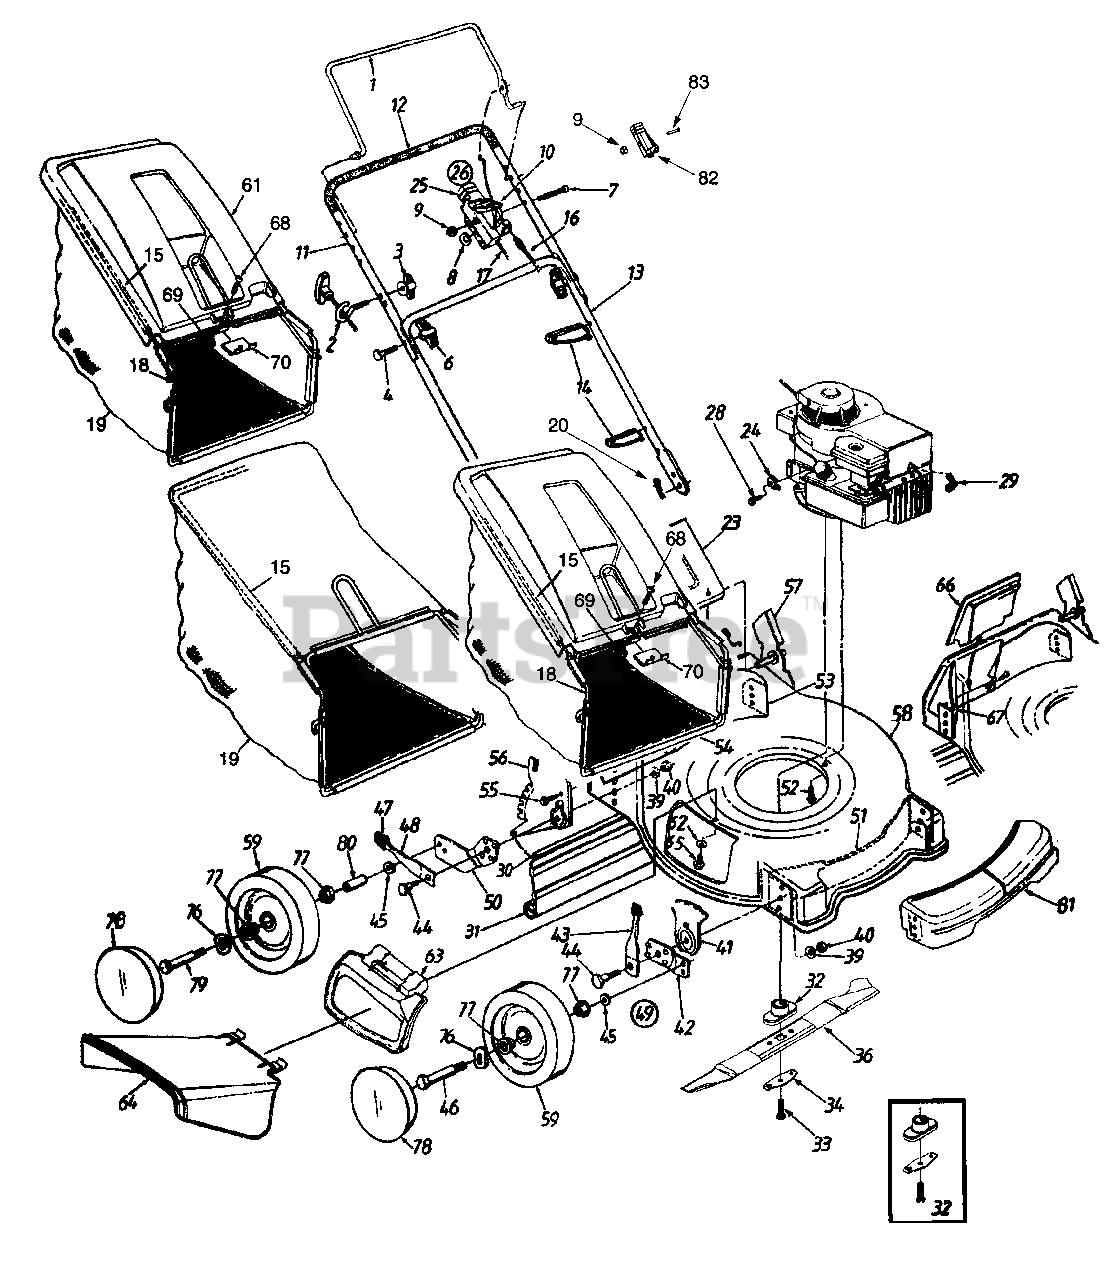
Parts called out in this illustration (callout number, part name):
1	Control Handle Ass'y. (Deluxe)
2	Rope Guide
3	Handle Knob 1/4-20 Thd.
4	Curved Hd. Bolt 5/16-18 x 2" Lg.
6	Hand Knob
7	Oval C-Sunk Mach. Scr.
8	Spr. Wash..66" I.D.
9	Hex L-Nut 1/4-20 Thd.
10	Throttle Lever
14	Cable Tie
16	Control Cable - 51"
17	Throttle Control Wire - 42"
20	Int. Cotter Pin 5/16" Dia.
25	Throttle Body
26	Throttle Box
28	Hex Slot Scr. #10-32: .38 Lg. (Tec.)
29	Spark Plug Boot
30	Wire Rod
31	Rear Flap
32	Blade Adapter Kit
33	Hex Bolt 3/8-24 x 1.5" Lg.
34	Blade Bell Support
36	21" Mulching Blade
39	Bell-Wash..39" I.D. x 1.38"
40	Hex Nut 3/8-16 Thd.
41	Height Adj. Plate
43	Spring Lever Ass'y. w/Knob
44	Shld. Bolt .5" Dia. x .357"
45	Bell-Wash..38" I.D. x .88" O.D.
46	Front Axle Bolt
47	Spring Lever Knob
48	Spring Lever
49	Height Adj. Ass'y. Comp. - R.H.
50	Pivot Bar R.H.
54	Torx Mach AB-Tap Scr. 1/4 x.62" L.
55	Hex Ind Wash. Scr. 1/4-14:.625
61	Hard Top Cover w/ Icon
62	Bell-Washer 1/4" I.D.
63	Hinged Mulching Plug
64	Chute Deflector
65	Hex Hd Self-Tp Scr. 1/4-20 x .5" L.
66	Mulching Baffle Plug
68	Pan Hd. Mach. Scr. 1/4-20:.5" Lg.
69	Hx. Nylon L-Nut - 1/4-20 Thread
76	Wave Washer
77	Ball Bearings (2 Req'd.)
78	Hub Cap - Rad. Spoke - Grey
79	Rear Axle Bolt
80	Spacer
81	Cover - Front End - Black
82	Throttle Housing w/o Lever
83	Screw 1/4-20 x 1.31
